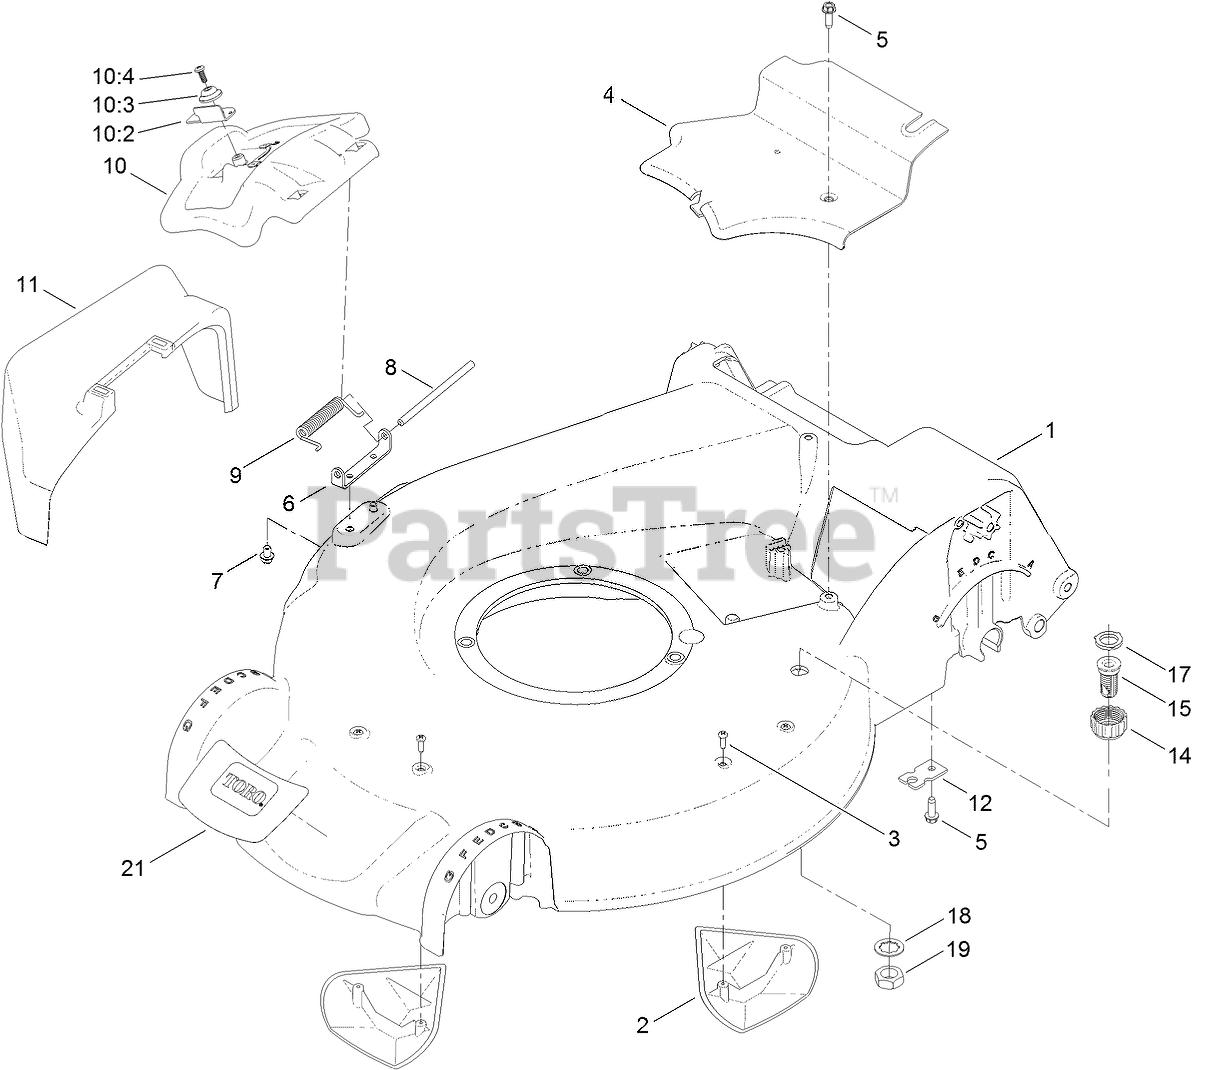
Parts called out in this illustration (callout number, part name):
1	HOUSING ASM
2	KICKER-HOUSING
3	SCREW-PPH
4	COVER-BELT
5	SCREW-HWHTF
6	BRACKET-COVER
7	SCREW-HWH
8	ROD-COVER
9	SPRING-TORSION
10	DISCHARGE DOOR ASM
10:2	LATCH-DOOR
10:3	CAP-DOOR
10:4	SCREW-PLASTITE
11	CHUTE-DISCHARGE, SIDE
12	BRACKET-CABLE, TRACTION
14	COUPLING-HOSE, WASHOUT PORT
15	PORT-WASHOUT
17	WASHER-SEAL, WASHOUT PORT
18	WASHER-TOOTH, INTERNAL
19	NUT-JAM
21	DECAL-DECK
